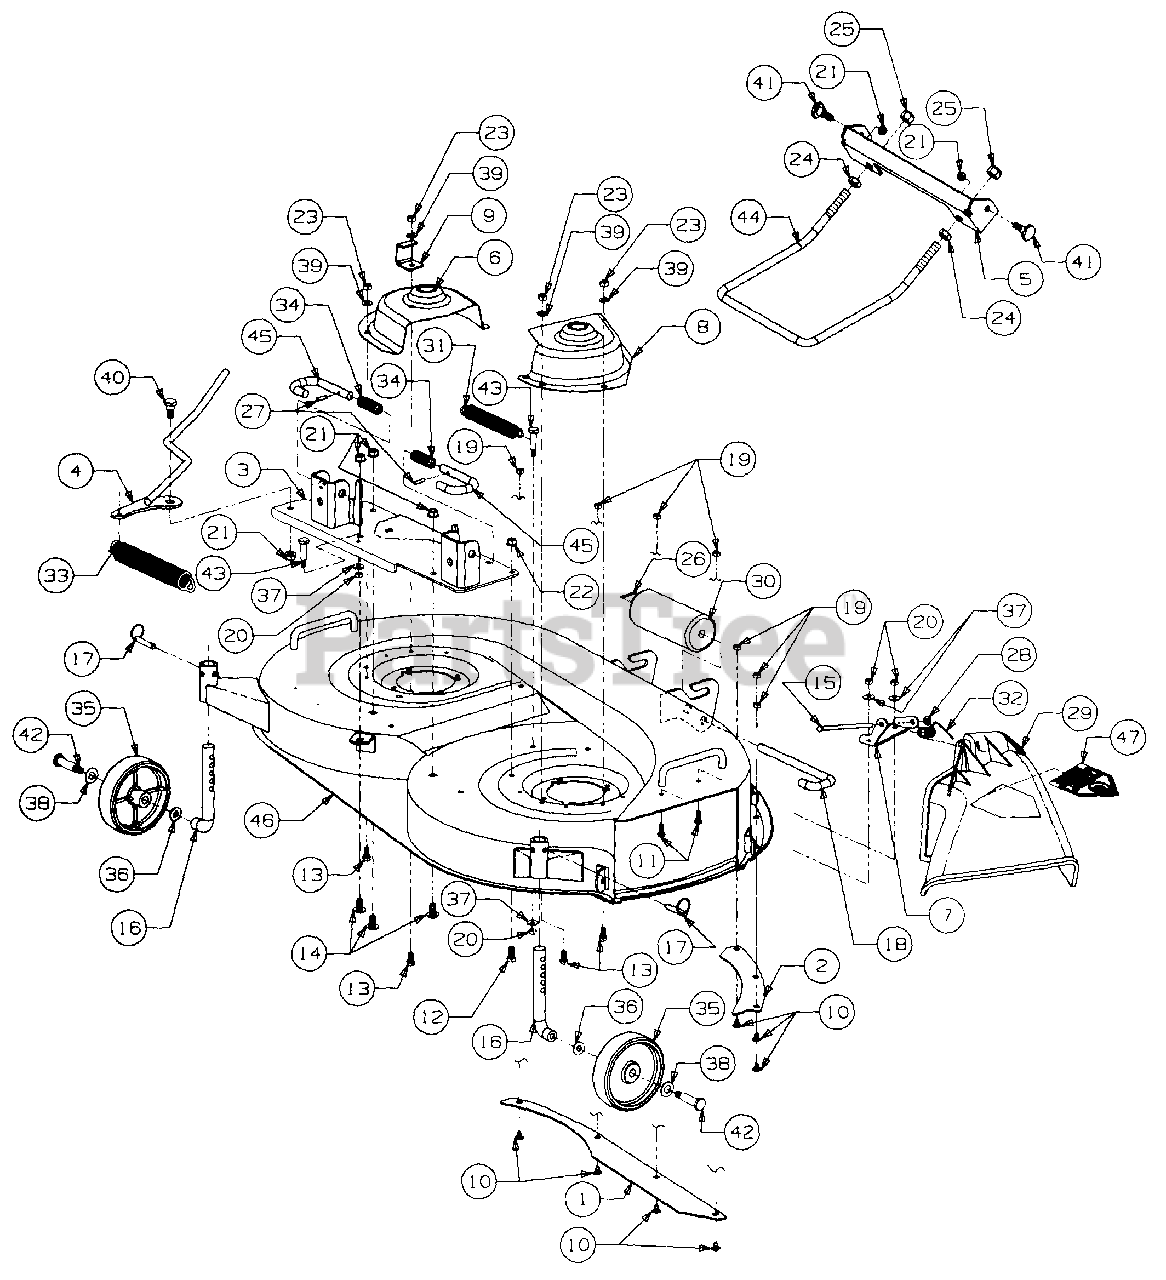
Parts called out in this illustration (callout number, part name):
1	Skirt, Extension
10	Bolt, Carriage, 1/4-20 x .50 Lg
11	Screw, Hex Cap, 1/4-20 x .62 Lg GR2
12	Screw, Hex Cap, 5/16-18 x .75 Lg GR5
13	Screw, Hex Cutting, 5/16-18 x .62 Lg
14	Bolt, Sht Nk Carriage, 3/8-16 x .75 Lg GR5
15	Pin, Hinge, .25 Dia x 6.75 Lg
16	Axle, Deck
17	Pin, Clevis w/Ball Detent
18	Pin, Roller, 1/2 Dia x 7.31 Lg
19	Nut, Hex Sems, 1/4-20
20	Nut, Hex, 1/4-20
21	Nut, Hex Flanged Lock, 3/8-16
22	Nut, Hex Flange Top Lock 5/16-18
23	Nut, Hex, 5/16-18 GR5
24	Nut, Hex Jam, 1/2-13 GR5
25	Nut, Hex Top Nylon Lock 1/2-13
26	Pin, Cotter, 1/8 Dia x 1.0 Lg
27	Pin, Spirol Spring, 3/16 Dia x .75 Lg
28	Cap, Speed Nut
29	Deflector Assy, Chute
31	Spring, Extension, .88 OD x 6.12 Lg
32	Spring, Torsion
33	Spring, Extension, 1.25 OD x 8.15 Lg
34	Spring, Compression
35	Wheel, Deck, 5 in. Dia
36	Washer, Bell, .380 x .88 x .062 Thk
37	Washer, Bell, .265 x .75 x .062 Thk
38	Washer, Flat, .510 x 1.0 x .060 Thk
39	Washer, Flat, .34 x .68 x .062 Thk
40	Bolt, Shoulder, .498 Dia x .340 Lg
41	Bolt, Shoulder, .50 Dia x .434 Lg
42	Bolt, Shoulder, .498 Dia x 1.64 Lg
43	Bolt, Shoulder, .375 Dia x 1.16 Lg
44	Rod, Front Lift
45	Pin, Mower Support
46	Deck Assy w/Graphics
47	Graphic, Danger
